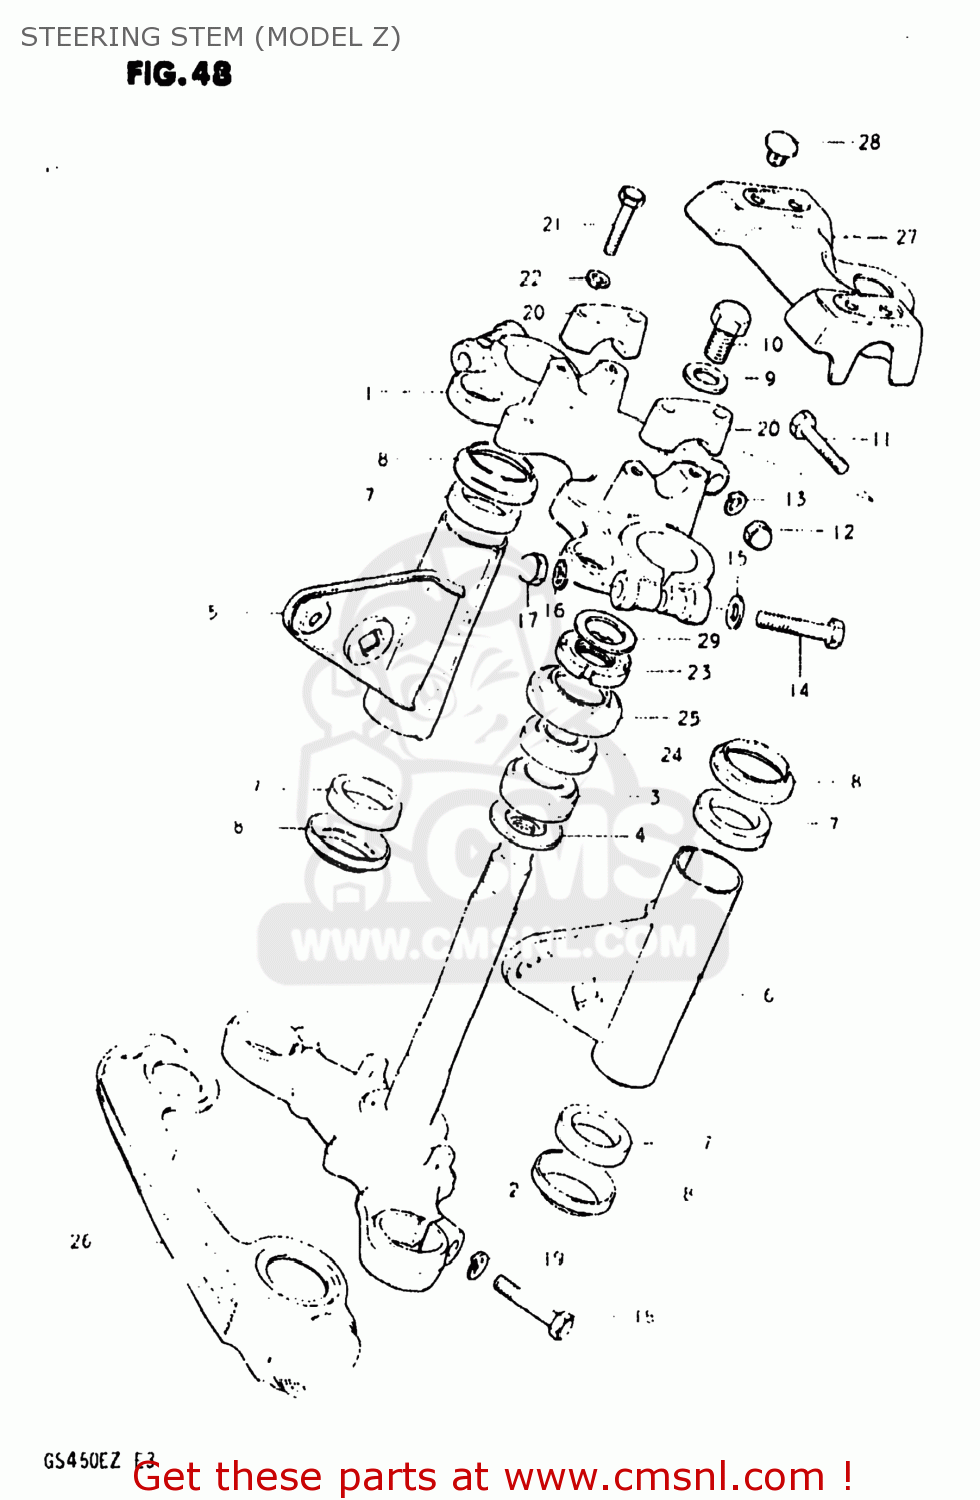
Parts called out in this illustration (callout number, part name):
1	HEAD,STEERING STEM
2	STEM,STEERING
3	BEARING
4	WASHER,THRUST
5	BRACKET,HEADLAMP,RIGHT
6	BRACKET,HEADLAMP,LEFT
7	CUSHION,HEADLAMP BRACKET
8	CAP,HEADLAMP BRACKET
9	WASHER
10	BOLT(12X20)
11	BOLT
12	NUT
13	LOCK WASHER
14	BOLT 10X55
15	WASHER
16	LOCK WASHER
17	NUT
18	BOLT 10X40
19	LOCK WASHER
20	HOLDER,HANDLE UPR
21	BOLT 8X35
22	WASHER,LOCK,8.
23	NUT,STEERING STEM
24	TAPER,ROLLER BEARING
25	DUST SEAL,STEERING,UPPER
26	COVER,FR FORK
27	PAD,HANDLE
28	CAP(OD:19.5)
29	WASHER(18.5X24X1)
